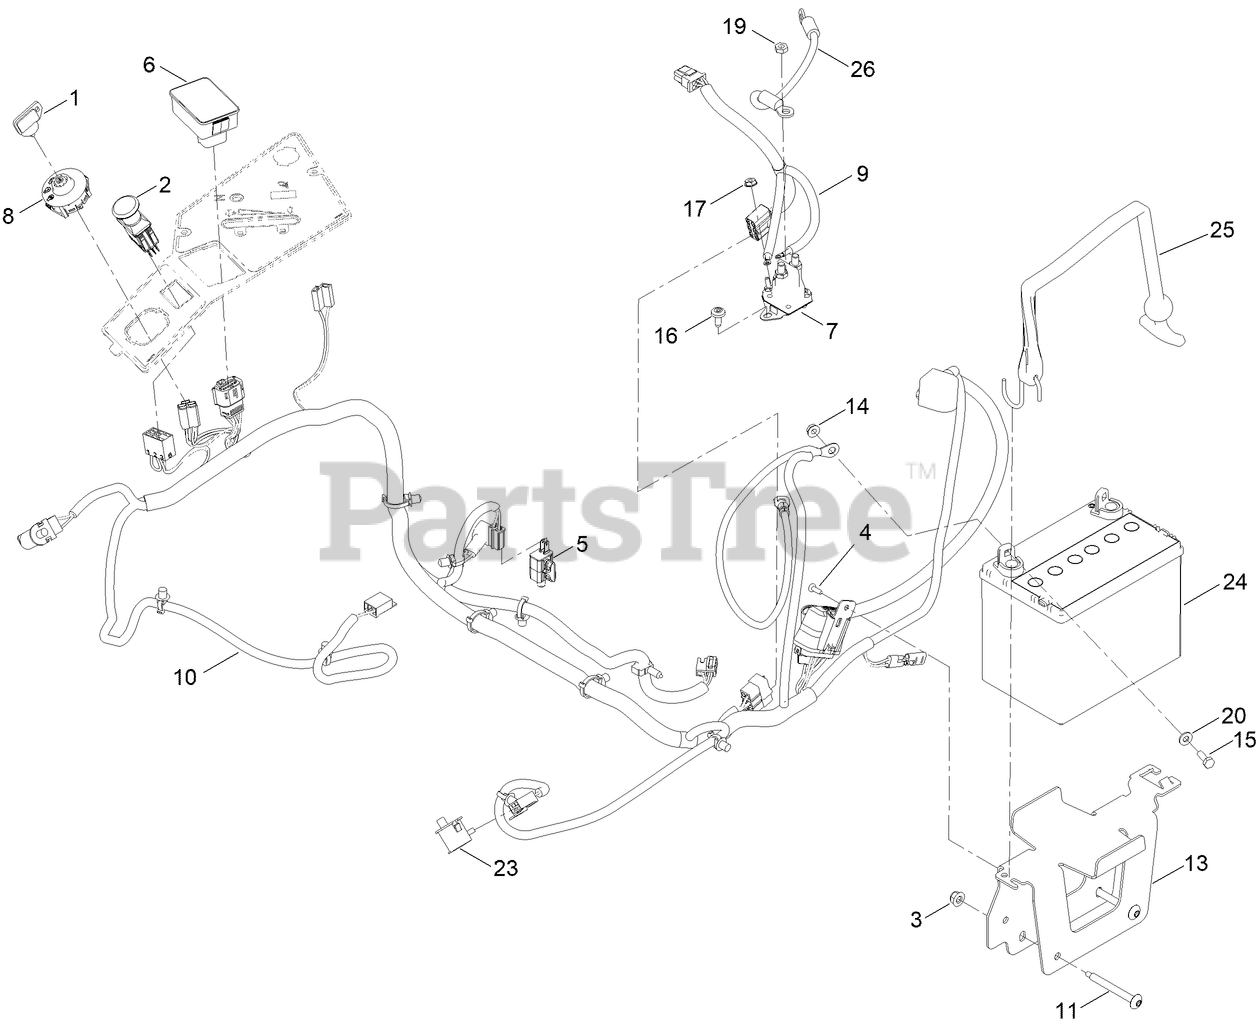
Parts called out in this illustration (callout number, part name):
1	KEY-IGNITION
2	SWITCH-PTO
3	NUT-HF, NI
4	SCREW-FORMING, THREAD
5	SWITCH
6	MODULE ASM
7	SOLENOID
8	SWITCH-IGNITION
9	ADAPTER-HARNESS, WIRE
10	HARNESS-WIRE
11	SCREW-TORX
13	TRAY-BATTERY
14	NUT-HF
15	SCREW-HH
16	SCREW-TORX
17	NUT-KEPS
19	NUT-JAM
20	WASHER-FLAT
23	SWITCH-BAIL
24	BATTERY- WET, 12V, 300 CCA
25	STRAP, BUNGEE
26	CABLE-BATTERY, POSITIVE
